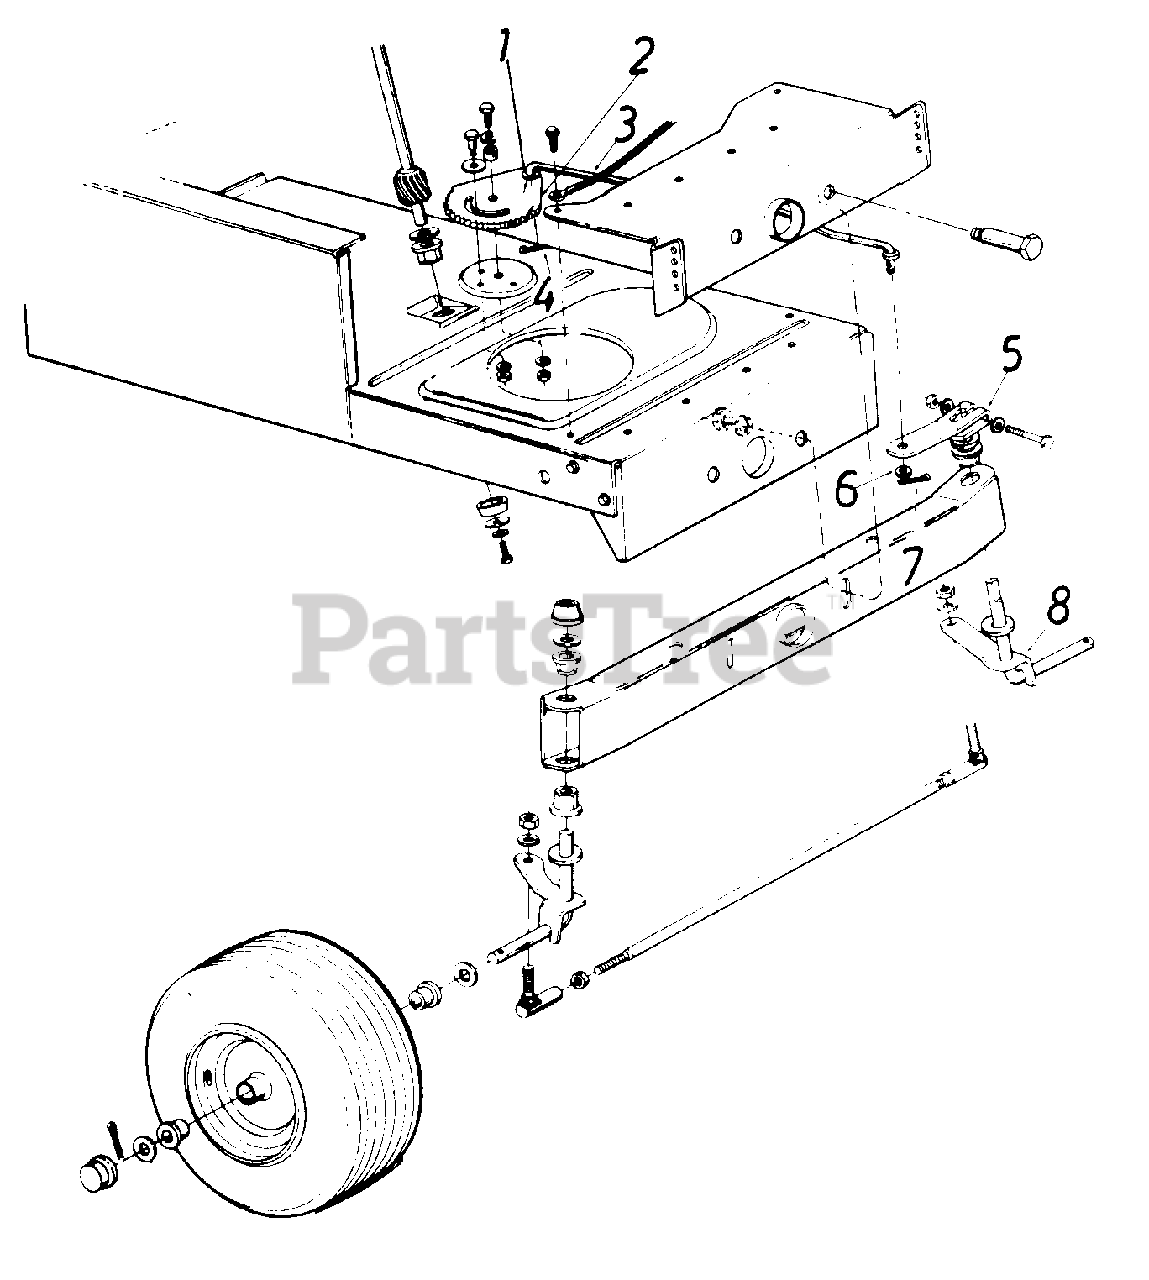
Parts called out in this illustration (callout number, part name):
1	Fl.-Wash. .56" I.D. x 1 " O.D.
2	Steering Gear Segment
3	Steering Drag Link
4	Cotter Pin 1/8" Dia. x 1 " Lg.
5	Steering Arm Front Axle
6	Fl.-Wash. .56" I.D. x 1" O.D.
7	Cotter Pin 1/8" Dia. x 1 " Lg.
8	Front Axle Ass'y . - L.H . - Short
